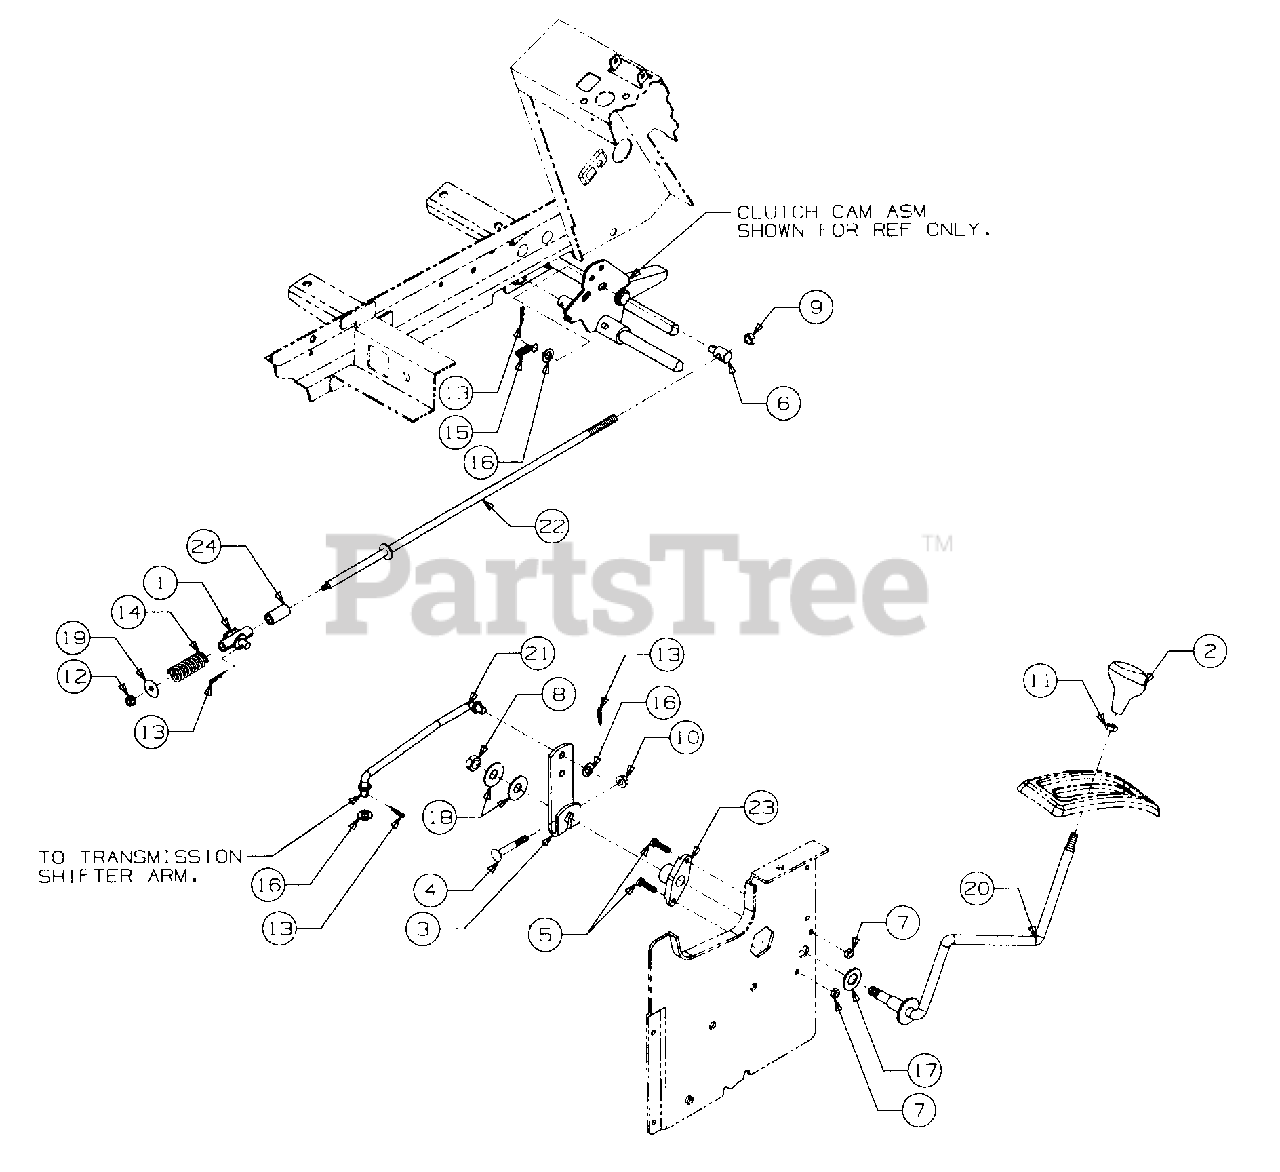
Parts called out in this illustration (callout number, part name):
1	Pivot Assy, Sleeve
2	Knob, Shifter
3	Bracket, Gear Shift
4	Bolt, Carriage, 5/16-18 x 2.25 Lg GR5
5	Screw, Hex Cap, 1/4-20 x 1.0 Lg
6	Ferrule, Adjustment
7	Nut, Hex Sems, 1/4-20
8	Nut, Hex Jam Lock, 1/2-20
9	Nut, Hex Jam, 3/8-24 GR5
10	Nut, Hex Flange Top Lock 5/16-18
11	Nut, Hex Jam, 3/8-16 GR5
12	Nut, Hex Flange Lock, 1/4-20
13	Pin, Internal Cotter, 5/16 Dia x 1.12 Lg
14	Spring, Compression, .63 ID x 2.0 Lg
15	Spring Extension, .38 OD x 1.44 Lg
16	Washer, Flat, .406 x .75 x .063 Thk
17	Washer, Flat, .64 x 1.25 x .100 Thk
18	Washer, Bell
19	Washer, Flat, .265 x 1.0 x .030 Thk Hdn
20	Lever, Speed Control
21	Rod, Gear Shift
22	Rod, Clutch Adjustment
23	Bushing, Control Lever
24	Spacer, .39 ID x .63 OD x 1.25 Lg
